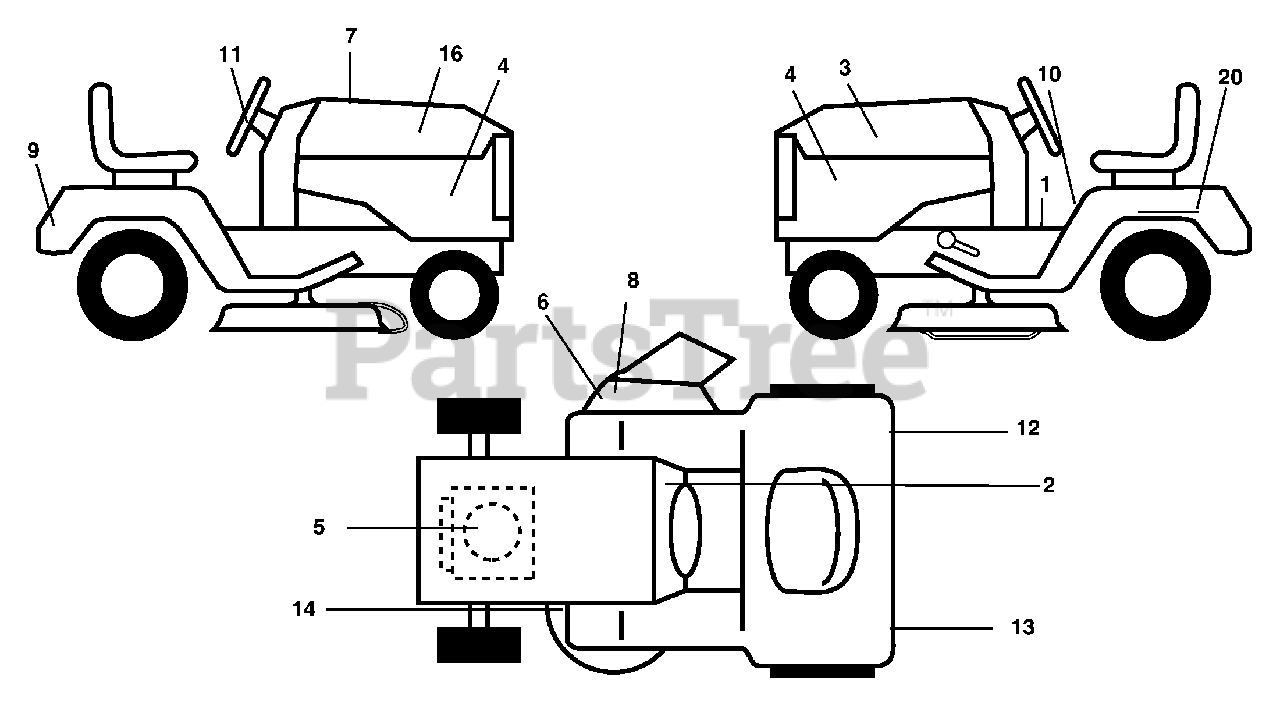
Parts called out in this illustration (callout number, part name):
1	Decal Oper
2	Decal SDPNL
3	Decal Hood LH
4	Decal Side Panel Logo
5	Decal Engine
6	Decal Warning, Keep Hand Away
7	Decal Replacement Parts
8	Decal Deck "B" 42"
9	Decal Fender Logo
10	Decal Fender Danger E/F
11	Decal Ins Strg Whl
12	Fend Reflector RH
13	Fend Reflector LH
14	Decal V-Belt Schematic
16	Decal Hood Rh
20	Decal Bat Dan/Psn
